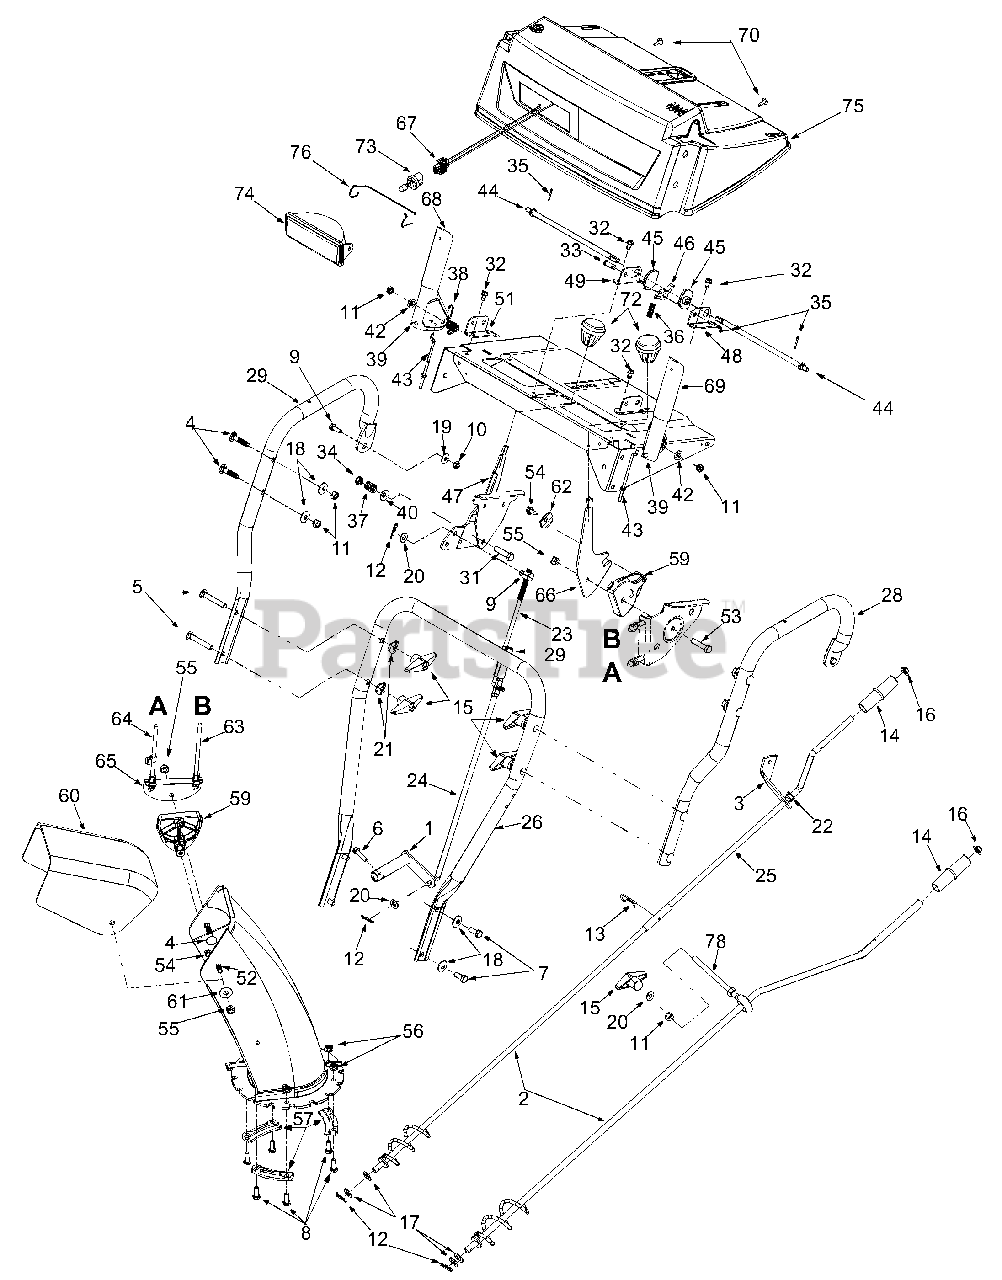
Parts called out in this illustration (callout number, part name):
4	Carriage Bolt, 5/16-18 x 1.5
5	Carriage Bolt, 5/16-18 x 2.25
6	Self Tapping Screw, 1/4-20 x 1
7	Hex Cap Screw, 5/16-18 x .75
8	Hex Cap Screw, 1/4-20 x .75
9	Ferrule, 5/16-18 x .312
10	Hex Nut, 1/4-20
11	Lock Nut
12	Internal Cotter Pin
13	Click Pin
14	Chute Crank Knob
15	Wing Knob, 5/16-18
16	Push Cap, 3/8
17	Flat Washer, .375 x .738 x .063
18	Bell Washer, .34 x .872
19	Bell Washer, .265 x .75 x .062
20	Flat Washer, .344 x .688 x .065
21	Saddle Washer, .32 x .93
22	Plastic Bushing
23	Upper Shift Rod
24	Lower Shift Rod
31	Hex Cap Screw, 3/8-24 x 1.5
32	Self Tapping Screw, 1/4-20 x .5
33	Clevis Pin
34	Jam Nut, 3/8-24
35	Cotter Pin
36	Compression Spring, .36 x 1.0
37	Comp. Spring, .39 x .6 x .88
38	Torsion Spring, .44 x .8
39	Rubber Bumper
40	Bell Washer, .401 x .87 x .063
42	Special Washer, .35 x .72 x .13
43	"Z" Fitting For Control Cables
44	Cam Rod
45	Cam Handle Lock
46	Handle Lock Pawl
52	Carriage Bolt, 5/16-18 x .75
53	Hex Cap Screw, 5/16-18 x 1.5
54	Screw, 1/4-14 x .625
55	Hex Lock Nut, 5/16-18
56	Hex Flange Lock Nut, 1/4-20
57	Lower Chute Flange Keeper
59	Chute Tilt Cable Guide
60	Upper Chute
61	Washer, 5/16
62	Special Washer, .28 x 1.2 x .06
63	Chute Deflector Control Cable
64	Chute Deflector Cable w/ Clip
67	Halogen Light Harness
68	RH Engagement Handle Ass'y
69	LH Engagement Handle Ass'y
70	Special Screw, #10-16 x .625
72	Plastic Knob
73	Halogen Lamp, 12-volt, 27 Watt
74	Lens Assembly / Lamp Housing
75	Handle Pane w/Tiltl, Yellow
76	Headlamp Retainer
78	Eyebolt
